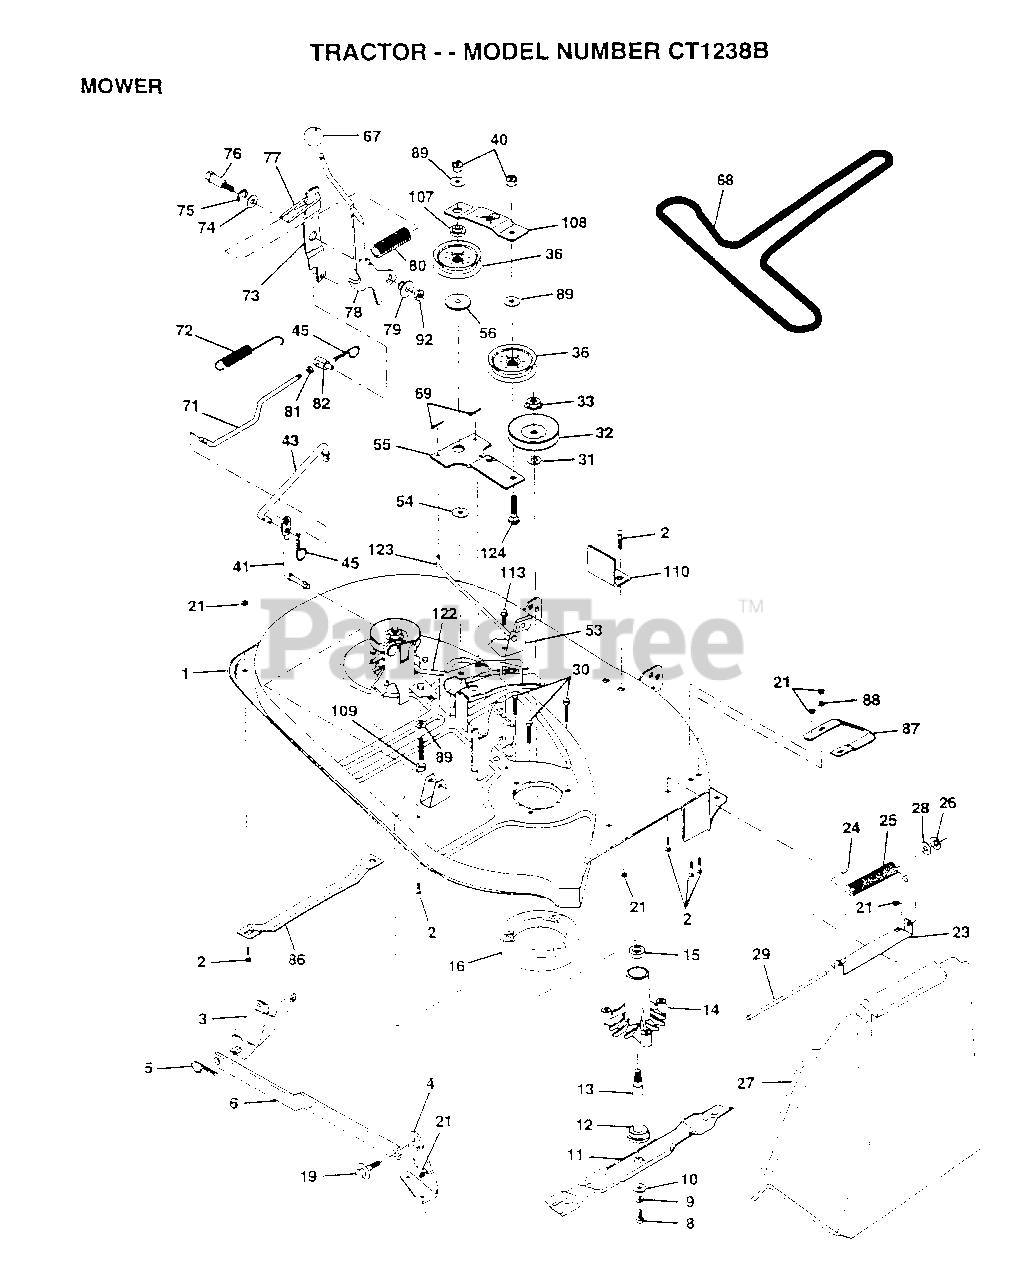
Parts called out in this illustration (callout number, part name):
2	BOLT
3	BRKT ASM SWAY BAR
4	BRKT DECK SW BAR
8	BLADE BOLT
10	WASHER.HARD.BLADE
11	"BLADE.38"" HIPERF"
12	BEARING.BALL
14	HSG ASM MANDREL
15	BEARING
16	STRIPPER RND MWR
19	BOLT SHD 5/16-18
23	BRKT DEFLECTOR
24	CAP-SLEEVE LT
25	SPRING TORSION
26	NUT PUSH M
27	DEFLECTOR-SHLD T
28	WASHER
29	ROD-HINGE T
31	WASHER
36	FLAT IDLER PULLEY
41	PIVOT ROD
43	CLUTCH ROD SECOND
45	RETAINER M
53	BRAKE ASM
54	HARDENED WASHER
55	IDLER ARM ASSY
56	SPACER RETAINER
67	KNOB T(3/8 HOLE)
68	V BELT
71	ROD CLUTCH 38/42
72	RETURN SPRING
73	CLUTCH ARM SECOND
74	WASHER
75	RING
76	SHOULDER BOLT
77	SPRING KEEPER
79	BUSHING
81	NUT
82	TRUNION ADJ
86	RUNNER-LH M
87	RUNNER RH
88	WASHER M
89	WASHER GT
92	NUT
107	RETAINER SPACER
108	IDLER ARM STIFF
109	BOLT
110	UPSTOP DECK FT 38
113	SCREW
122	BRAKE ROD LH
123	BRAKE ROD RH
124	BOLT
